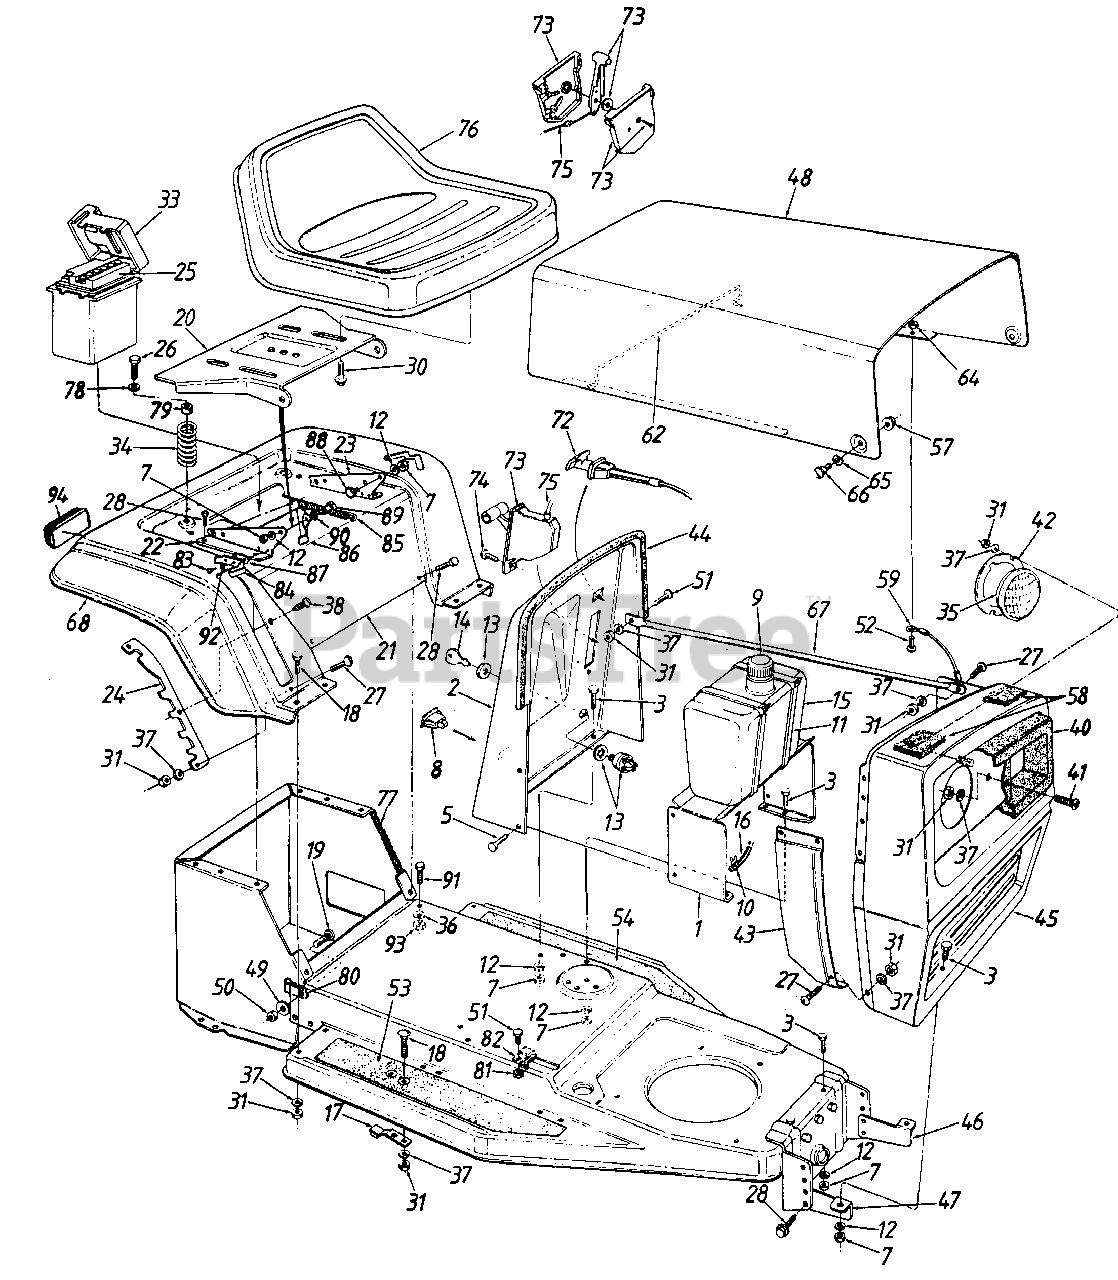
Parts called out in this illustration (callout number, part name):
1	Dash Panel Support Brkt.
5	Hex AB-Tap Scr. 1/4 x .62"
7	Hex Nut 5/16-18 Thd.
8	Light Switch
9	Gas Gauge
11	Cable Tie
12	L-Wash. 5/16" I.D.
13	Ignition Switch
14	Ignition Key
15	Fuel Tank
16	Gas Line
17	Blade Brake Ass'y.
18	Carriage Bolt 1/4-20 x .62"
19	Ribbed Neck Bolt 3/8-24 x .8"
20	Seat Pivot Brkt.
21	Rear Fender
22	Seat Hinge Support Brkt.-R.H.
23	Seat Hinge Support Brkt.-L.H.
24	Deck Lift Index Brkt.
25	Battery
26	Hex Self-Tap Screw 5/6-18 x 1.25" Lg.
27	Truss Mach. Scr. 1/4-20 x .75" Lg.
28	Hex AB-Tap Scr. 5/16 x .75" Lg.
30	Hex Self-Tap Scr. 3/8-16 x .75" Lg.
31	Hex Nut 1/4-20 Thd.*
33	Battery Box w/Cover
34	Compression Spring
35	Headlight
36	Bell-Wash. 5/16" I.D.
37	L-Wash. 1/4" I.D.*
38	Hex Wash. Hd. Tap Scr. #10 x .5" Lg.
41	C-Sunk Mach. Scr. 1/4-20 x 1.5"
42	Headlight Retainer
43	Side Panel-R.H.
44	Trim Strip 31" Lg.
47	Grille Mtg. Brkt.-R.H.
50	Hex L-Nut 3/8-24 Thd.
51	Hex Bolt 1/4-20 x .62" Lg.*
52	Truss Mach. Scr. #10-24 x .5" Lg.
53	Foot Pad-R.H.
54	Foot Pad-L.H.
57	Lock Nut 1/4-28 Thd.
64	Hex Sems Nut #10-24 Thd.
65	Spr. Wash. .39" I.D. x .62" O.D.
66	Shld. Bolt
67	Grille Support
68	Trim Strip 81" Lg.
72	Choke Control
73	Throttle Control Box
74	Truss AB-Tap Scr. #10 x .5"
75	Throttle Wire
76	Seat Assembly
77	Trim Strip 5" Lg.
78	Flat Wash. .344" I.D. x .88" O.D.
80	Clamp
81	Hex L-Nut 1/4-20 Thd.
83	Hex Tap Scr. #8 x .5" Lg.
84	Spring Switch
85	Ext. Spring 5.31" Lg.
86	Seat Lift Brkt.
87	Insulator Nut Plate
88	Shld. Bolt .437" Dia. x .162" Lg.
89	Shld. Bolt .437" Dia. x .268" Lg.
90	Spr. Wash. .445" I.D. x .75" O.D.
91	Hex Bolt 5/16-24 x .75" Lg.
92	Fiber Washer
93	Hex Nut 5/16-24 Thd.
94	Reflector
